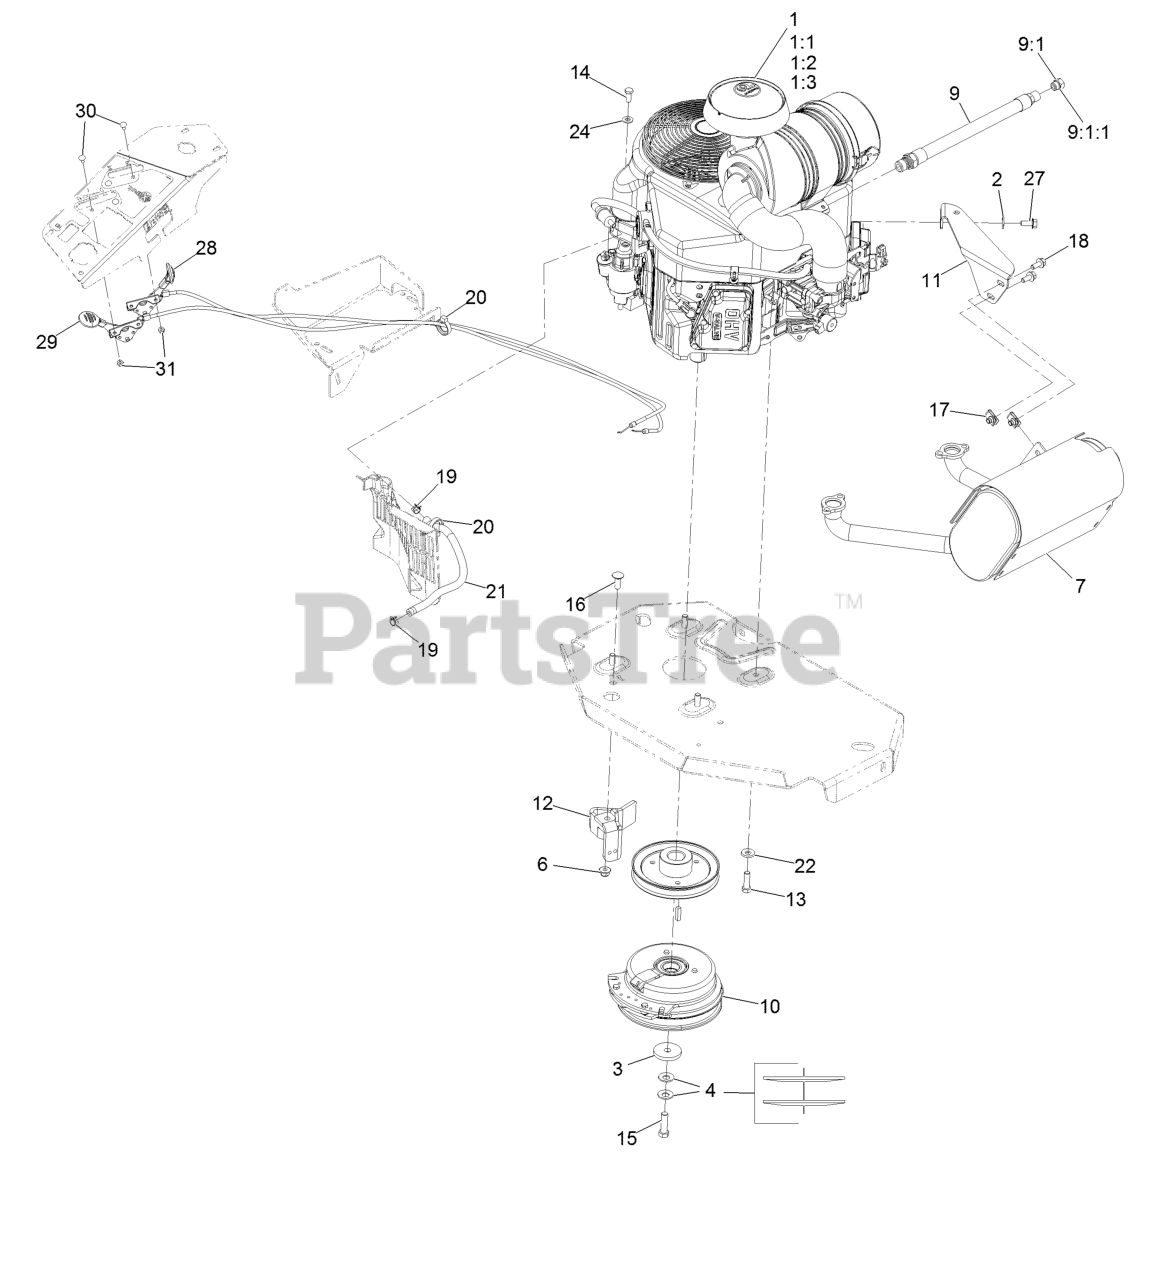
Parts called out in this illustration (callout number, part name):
1:1	Kawasaki 49065-7007 Engine Oil Filter
1:2	Kawasaki 11013-7044 Engine Air Filter
1:3	Kawasaki 11013-7045 Safety Filter
2	Washer-Spring Disc 5/16
3	Washer-Clutch
4	Washer-Spring Disc 7/16
6	Nut-Nyloc 3/8-16 Flg
7	Muffler
9	Asm-Hose Oil Drain W/Plug
9:1	Plug-W/O-Ring
9:1:1	O-Ring
10	Clutch Kit
11	Bracket-Muffler
12	Clutch-Anchor
13	Screw-HH 3/8-16 X 1 1/4
14	Screw-HH M8-1.25 X 20Mm
15	Screw-HH 7/16-20 X 1 1/2 W/Loctite
16	Bolt-Carriage 3/8-16 X 1
18	Screw-HH Flg 5/16-18 X 3/4
19	Clamp-Hose
20	Clamp-Hose
21	Hose-Fuel Line 15"
22	Washer-Spring Disc 3/8
27	Screw-HH M8-1.25 X 20Mm
28	ASM, Choke Cable
29	ASM,Throttle Cable
30	Bolt-Carriage #10-24 X 1/2
31	Nut-Nyloc #10-24
